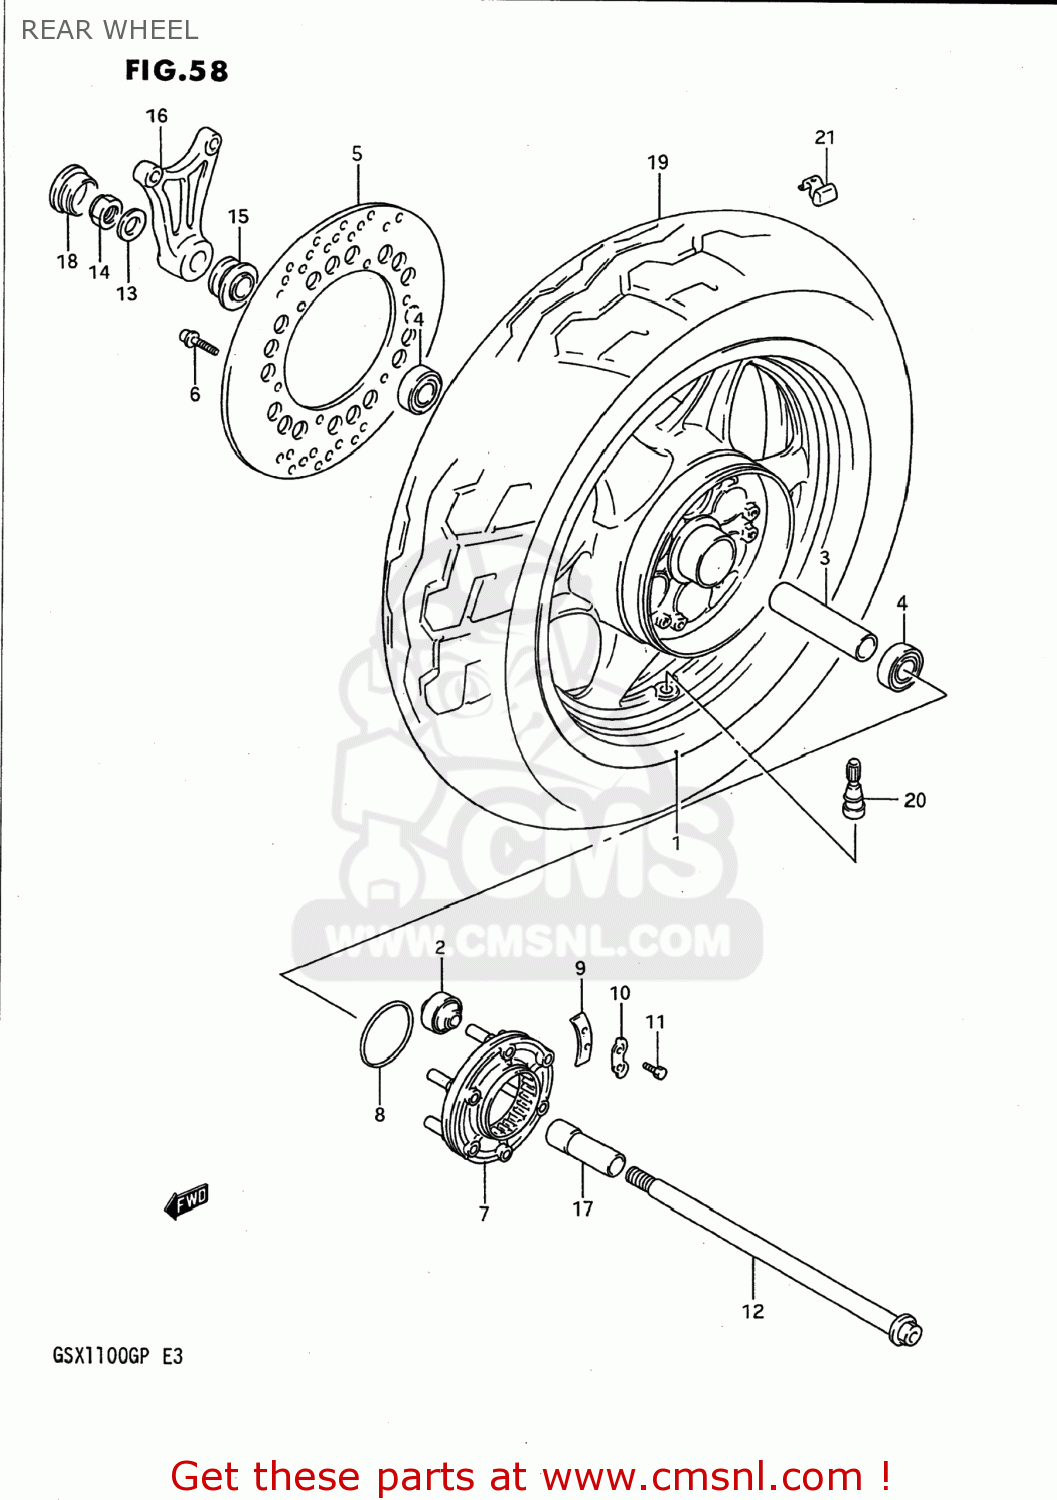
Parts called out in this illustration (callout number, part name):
1	WHEEL SET,REAR (17XMT4.50)
2	BUSH
3	SPACER(20.8X27.2X124)
4	BEARING(20X47X14)
5	DISC,RR BRAKE
6	BOLT, REAR
7	JOINT ASSY,RR HUB DRIVEN
8	O RING(D:2.1,ID:65)
9	WASHER,THRUST(T:1.6)
10	WASHER
11	BOLT(6X16)
12	AXLE,RR
13	WASHER
14	NUT
15	SPACER,RR AXLE,R
16	BRACKET,REAR CALIPER
17	SPACER,REAR AXLE,LEFT
18	CAP,RR AXLE,R
19	TIRE COMP,REAR 160/70
20	VALVE ASSY,WHEEL RIM(TR412)
21	BALANCER,WHEEL
